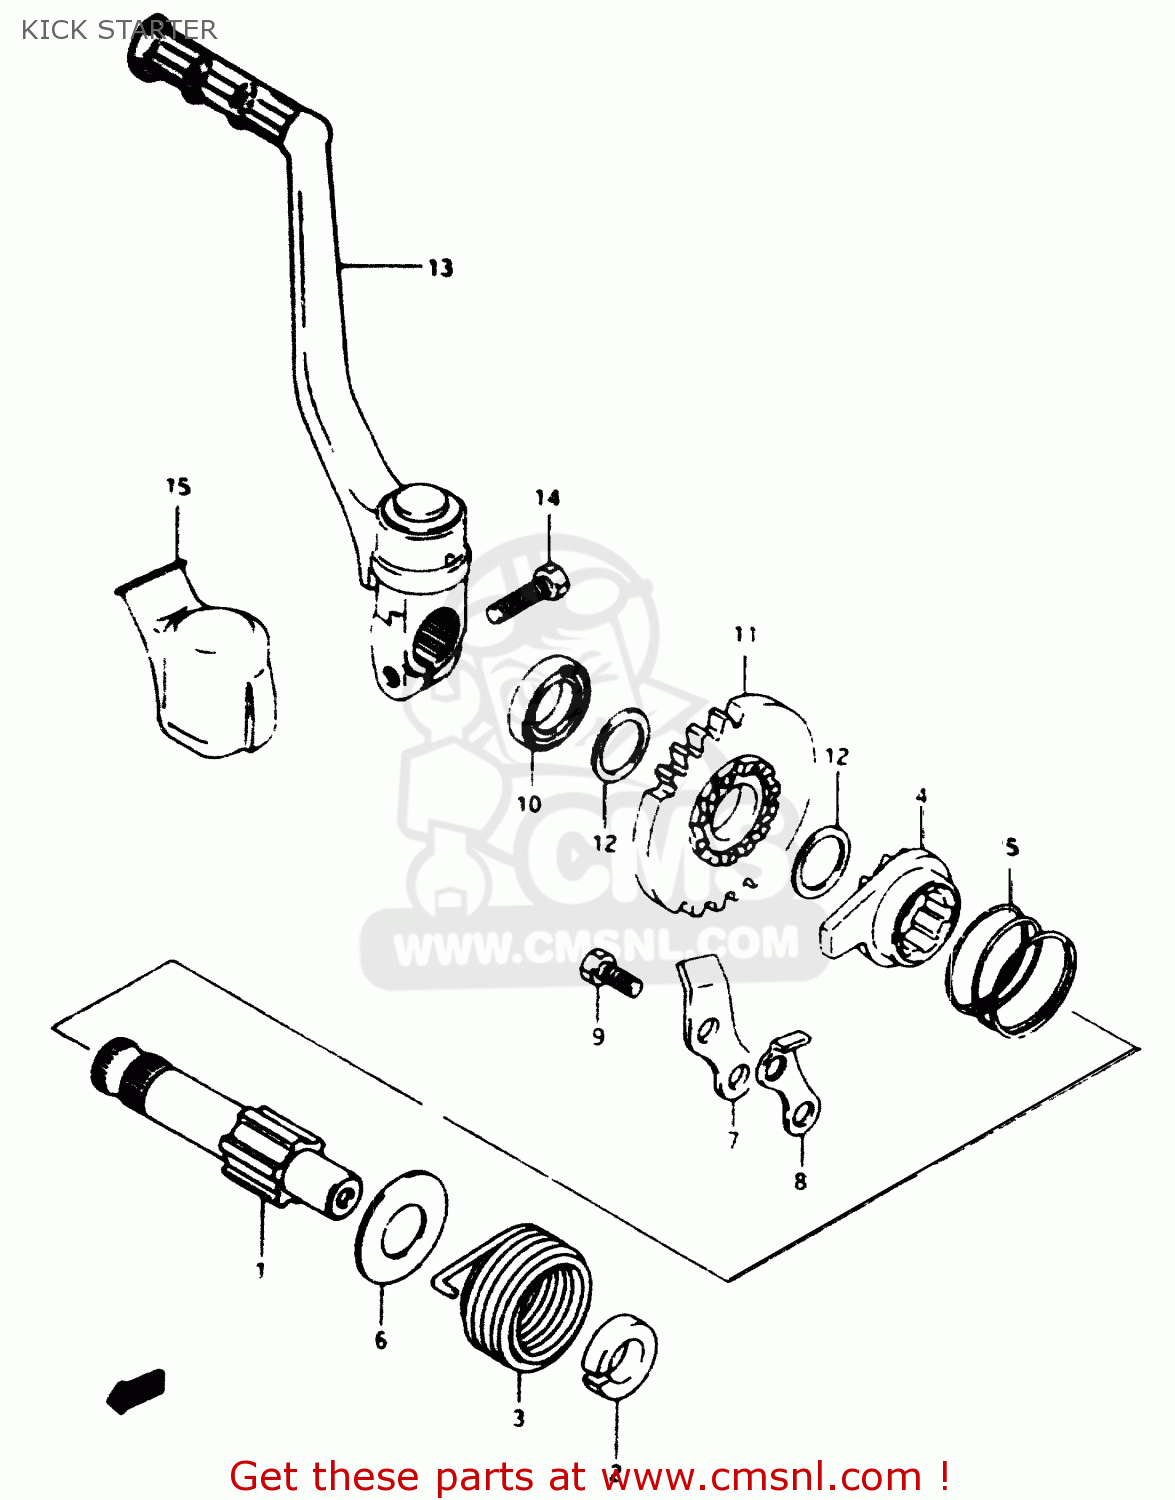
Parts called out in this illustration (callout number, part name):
1	SHAFT,KICK STARTER
2	GUIDE,SPRING
3	SPRING
4	STARTER,KICK
5	SPRING
6	WASHER
7	GUIDE,KICK STARTER
8	STOPPER,KICK STARTER
9	BOLT
10	SEAL,OIL(14X24X6)
11	GEAR,KICK STARTER DRIVE
12	WASHER
13	LEVER ASSY,KICK STARTER
14	BOLT
15	COVER,KICK LEVER JOINT
